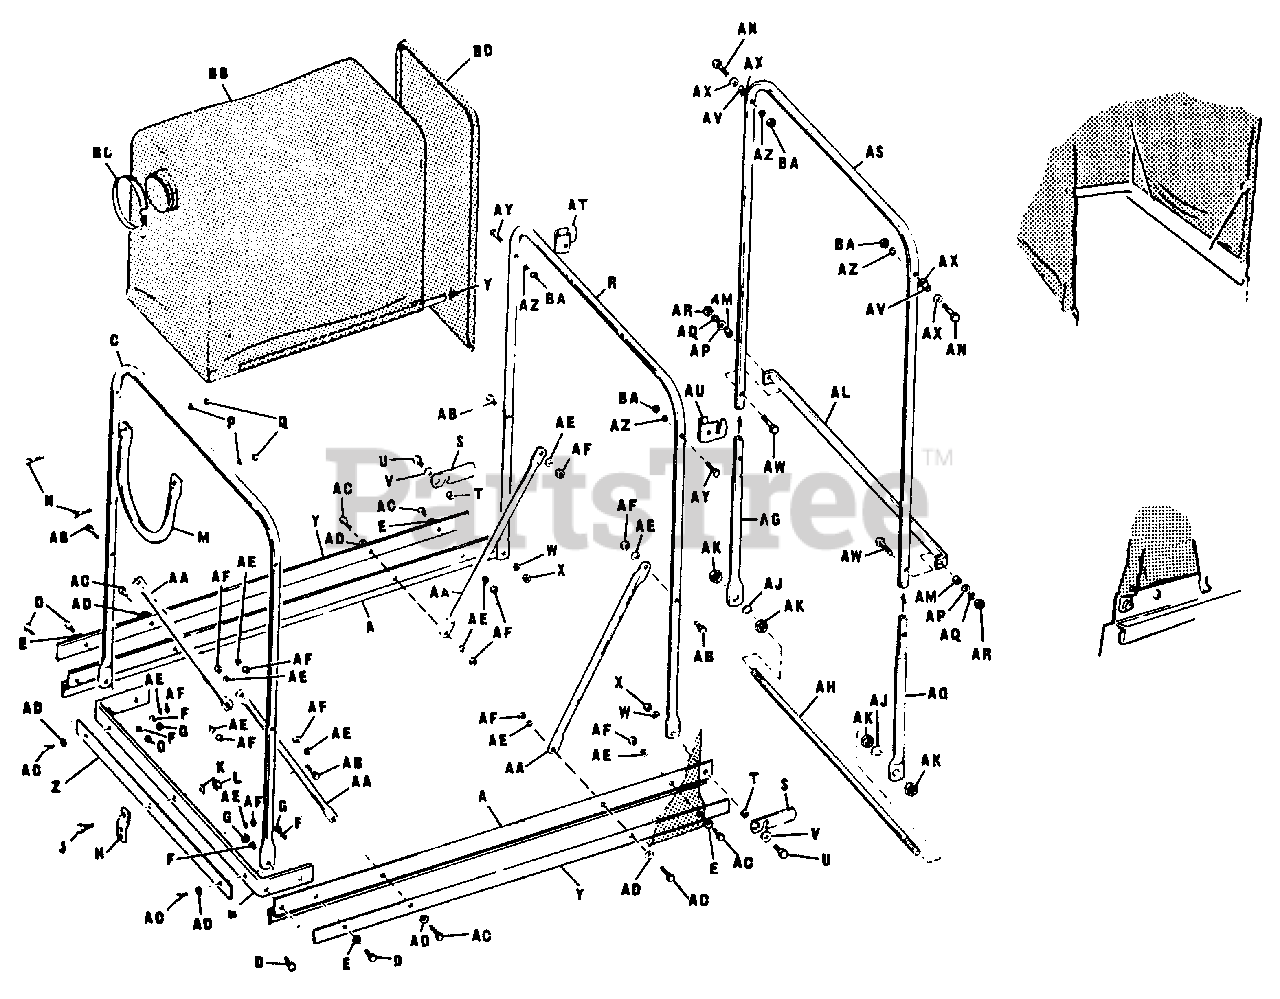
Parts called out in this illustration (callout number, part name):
A	"Z" Bar, Side
B	Front Bar
C	Front and Rear Upright
D	Hex Capscrew, 5/16"-18 x 1" lg.
E	Plain Washer, 5/16"
F	Lock Washer, 5/16"
G	Hex Nut, Full, 5/16"-18
J	Hex Capscrew, 3/8"-16 x 1" lg.
K	Plain Washer, 3/8"
L	Hex Lock Nut, Full, 3/8"-16
M	Hose Support
N	Hex Capscrew, 1/4"-20 x 1-1/4 lg.
P	Lock Washer, 1/4"
Q	Hex Nut, Full, 1/4"-20
R	Front and Rear Upright
S	Rear Door Latch
U	Hex Capscrew, 5/16"-18 x 7/8" lg.
V	Plain Washer, 5/16"
W	Lock Washer, 5/16"
X	Hex Nut. Full, 5/16"-18
Y	Hold Down Strip, Side
Z	Hold Down Strip Front
AA	Cross Brace Tube
AB	Hex Capscrew, 1/4"-20 x 1-1/4" lg.
AC	Hex capscrew, 1/4"-20 x 3/4" lg.
AD	Plain Washer, 1/4"
AE	Lock Washer, 1/4"
AF	Hex Nut, Full, 1/4"-20
AG	Tube, Rear Door
AH	Rod, Rear Door
AJ	Lock Washer, 1/2"
AK	Hex Nut, Full. 1/2"-13
AL	Bar, Rear Door
AN	Hex Capscrew. 1/4"-20 x 1-3/4" lg.
AP	Plain Washer. 1/4"
AQ	Lock Washer 1/4"
AR	Hex Nut. Full. 1/4"-20
AS	Top Rear Door
AT	Catch. Door. R.H.
AU	Catch. Dool. R.H.
AW	Hex Capscrew. 1/4"-20 x 1-3/4" lg.
AX	Plain Washer. 1/4"
AY	Hex Capscrew, 1/4"-20 x 1-1/4" lg.
AZ	Lock Washer. 1/4"
BA	Hex Nut. Full, 1/4"-20
BC	Hose Strap
